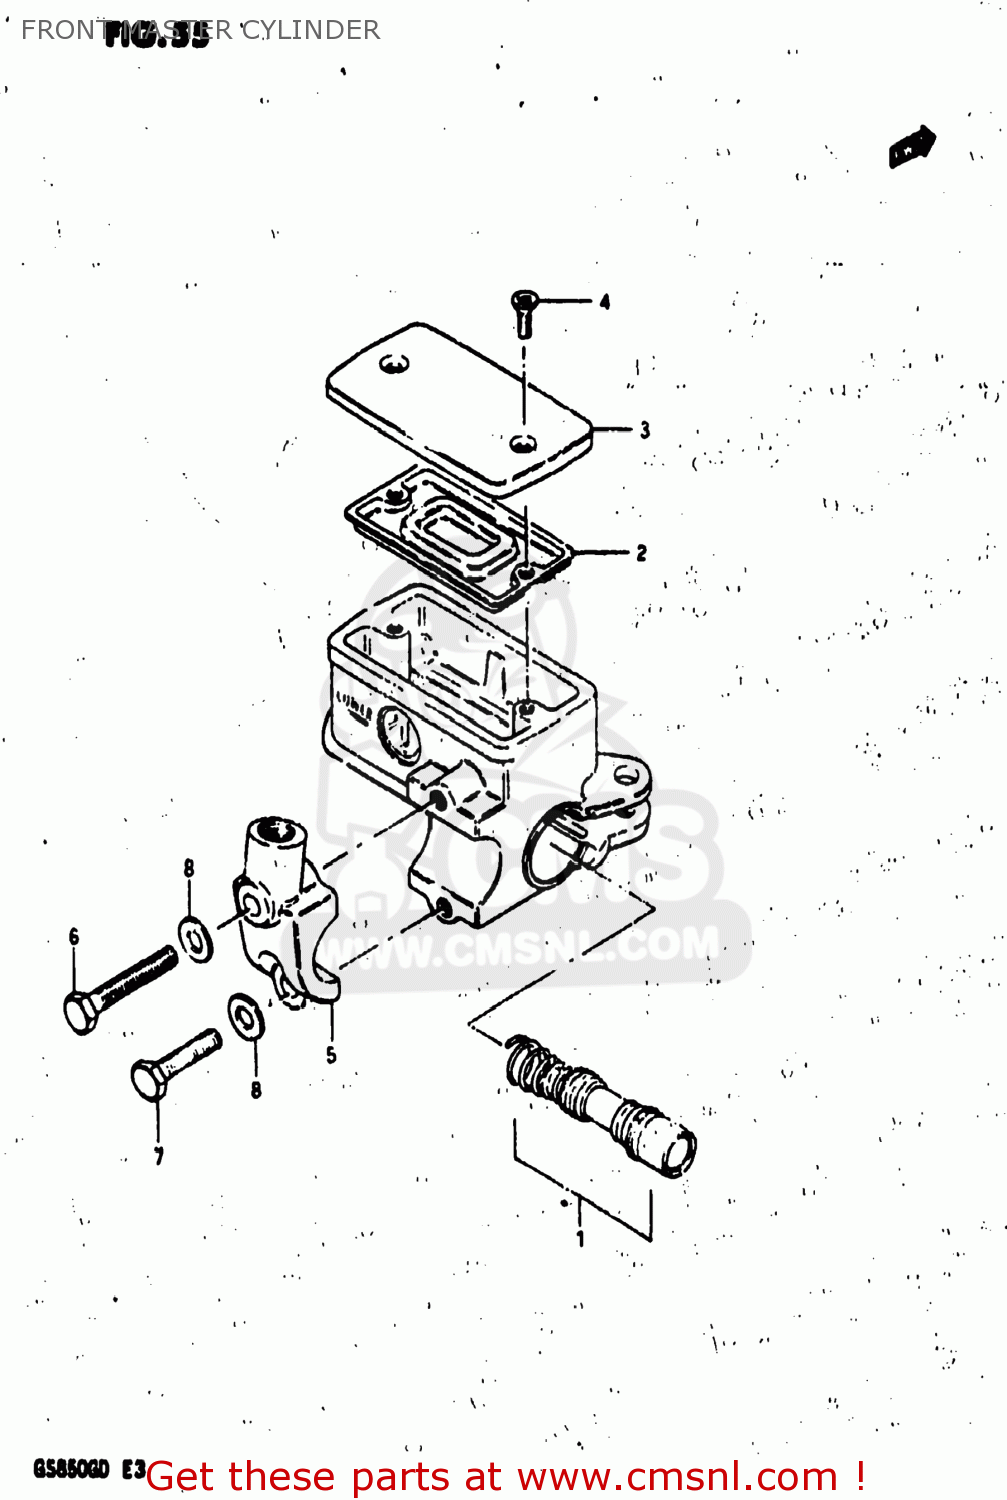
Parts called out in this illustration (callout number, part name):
1	PISTON & CUP SET
2	3
3	CAP
4	SCREW
5	HOLDER
6	BOLT 6X40
7	BOLT
8	WASHER
